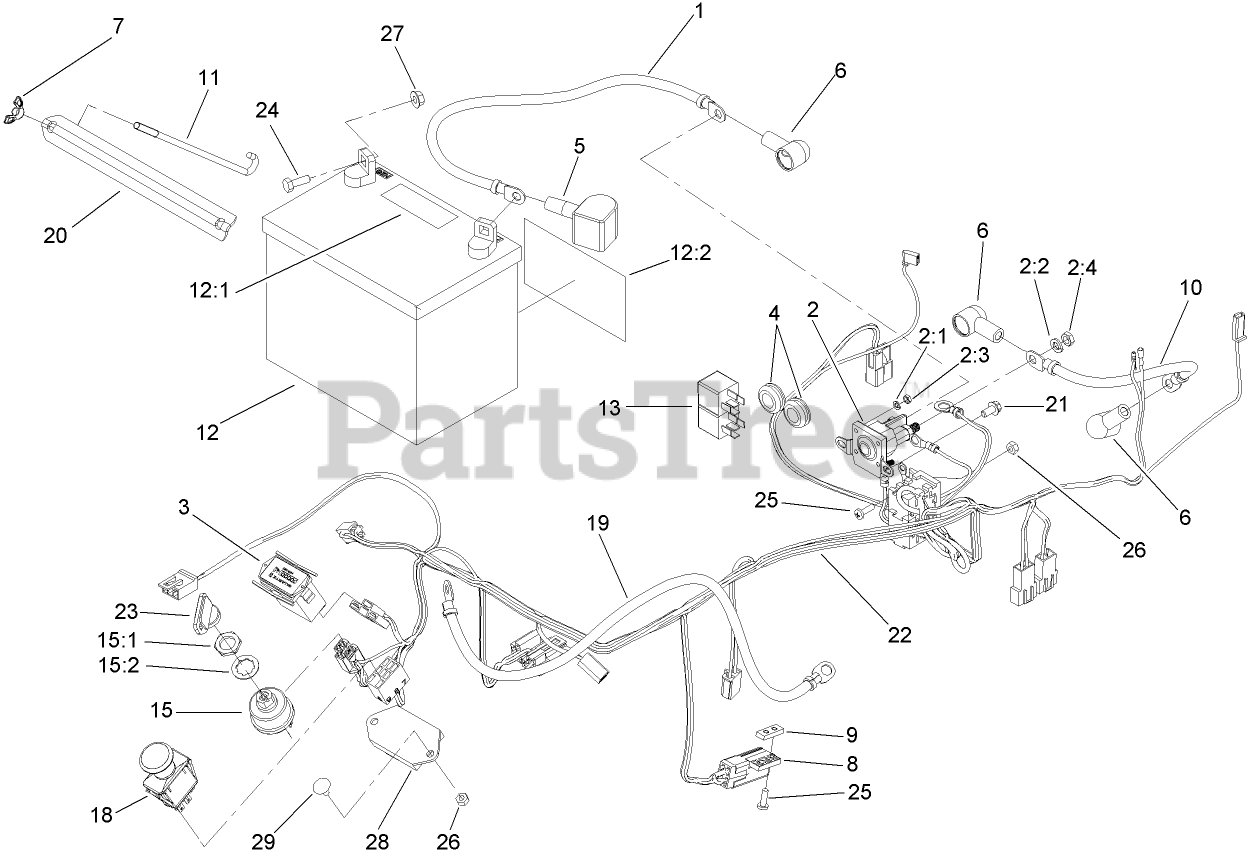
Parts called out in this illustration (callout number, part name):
1	CABLE-BATTERY, POSITIVE
2	SWITCH-SOLENOID
2:1	WASHER-LOCK
2:2	WASHER-LOCK
2:3	NUT-HEX
2:4	NUT-JAM
3	METER-HOUR
4	GROMMET
5	INSULATOR-BATTERY
6	INSULATOR-SOLENOID
7	WINGNUT
8	SWITCH
9	PLATE-TAPPED
10	CABLE-STARTER, POSITIVE
11	BOLT-HOLDDOWN
12	BATTERY
12:1	Decal-Battery
12:2	Decal-Battery
15	SWITCH ASM
15:1	NUT-HH
15:2	WASHER-TOOTH, INTERNAL
18	SWITCH-PTO
19	CABLE-BATTERY, NEGATIVE
20	ANGLE-BATTERY
21	SCREW-HWH
22	HARNESS-WIRE
23	KEY-IGNITION
24	SCREW-HH
25	SCREW-PPH
26	NUT-LOCK, NI
27	NUT-HF
28	MODULE-DELAY, SEAT
29	BOLT-CARR
